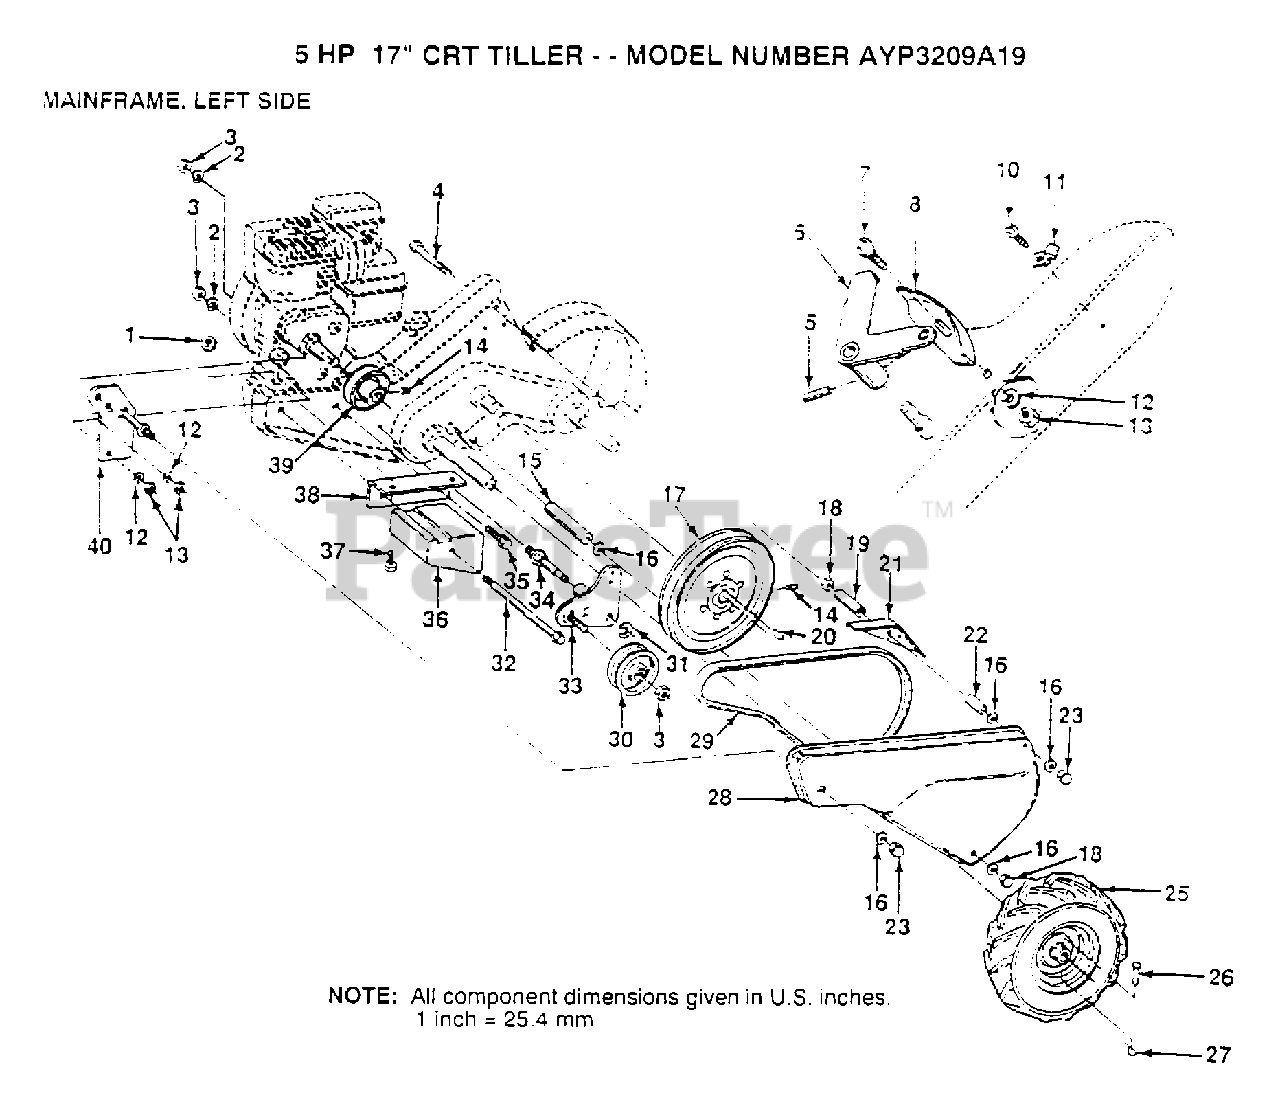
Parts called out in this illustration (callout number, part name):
2	LOCKWASHER
3	NUT.HEX.3/8-16UNC
4	BOLT-HEX TI
6	LEVER ASM CRT
7	BOLT
8	PANEL TI
11	CONDIUT CLIP T
12	LOCKWASHER
14	SET SCREW
15	SPACER
16	WASHER
17	"SHEAVE 10"" CRT"
18	NUT.HEX.5/16-18
19	SPACER CRT
20	KEY T
21	GUARD CRT
22	SPACER CRT
23	NUT TI
25	TIRE TI
26	RIVET.DRILL.1.75
27	RETAINER M
30	PULLEY-IDLER TI
31	KLIP RING
32	BOLT CRT
34	SHIFT ARM CRT
35	BOLT
36	COUNTERWEIGHT CRT
37	BOLT.HEX.5/16-1.5
38	BRACKET LH CRT
